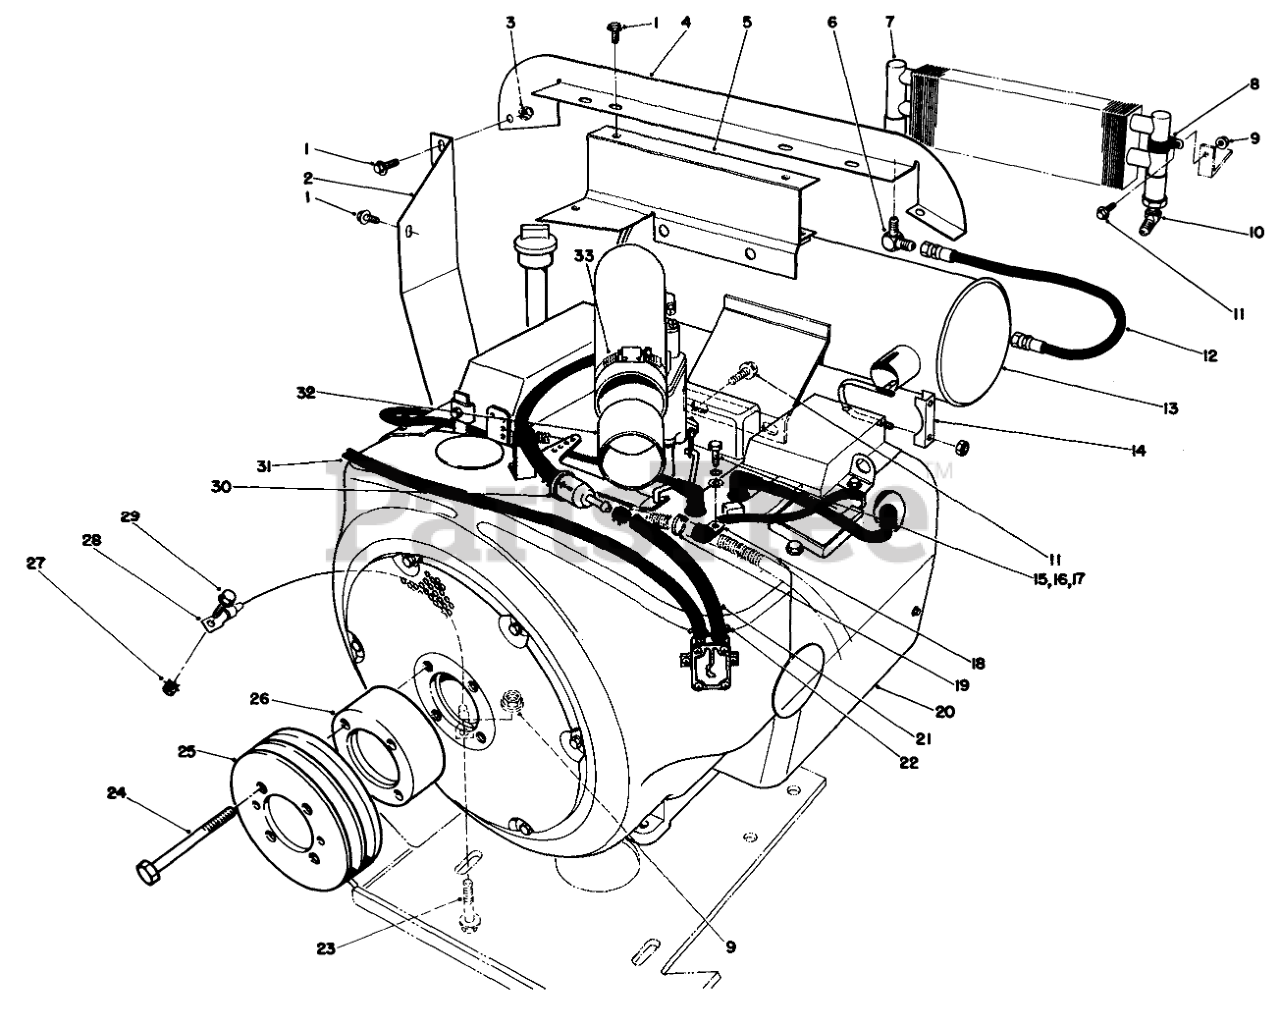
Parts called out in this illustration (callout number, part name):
1	SCREW-HHF
2	Shield-Heat
3	NUT-LOCK, NI
4	Shroud-Engine
5	Bracket-Shield Support
6	90DEG JIC FITTING
7	OIL COOLER
8	CLAMP-R
9	NUT-HHF, WHIZ
10	ELBOW
11	SCREW-HHF
12	OIL HOSE ASM
13	Muffler
14	MUFFLER CLAMP
15	SCREW-HH
16	WASHER-LOCK
17	WASHER-FLAT
18	CLAMP-R
19	TIE-CABLE
20	Engine (Onan Model No. P220G-I/10808C
21	Hose
22	CLAMP-HOSE
23	SCREW-HHF
24	SCREW
25	Pulley-Engine
26	PULLEY SPACER
27	NUT-KEPS
28	WIRE ASM
29	SCREW-HHF
30	FILTER-FUEL
31	HOSE
32	AIR CLEANER ADAPTER
33	CLAMP-HOSE
